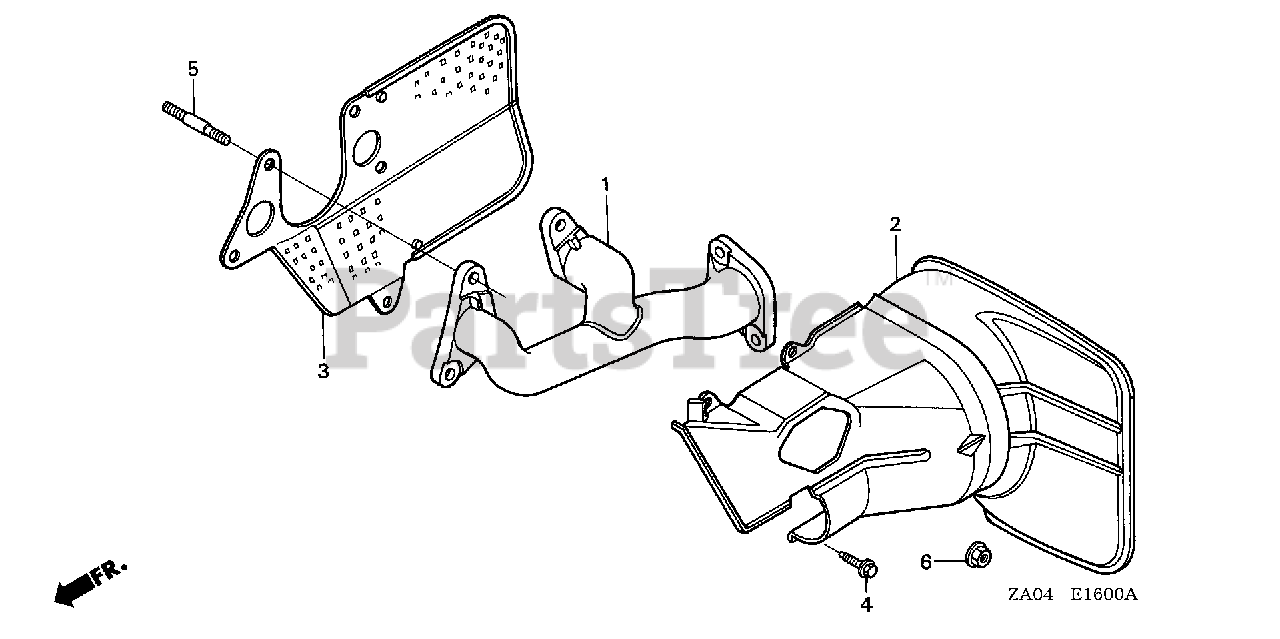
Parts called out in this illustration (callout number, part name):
1	MANIFOLD, EX.
3	GASKET, EX.
5	BOLT, STUD (8X35)
6	NUT, FLANGE (8MM)
